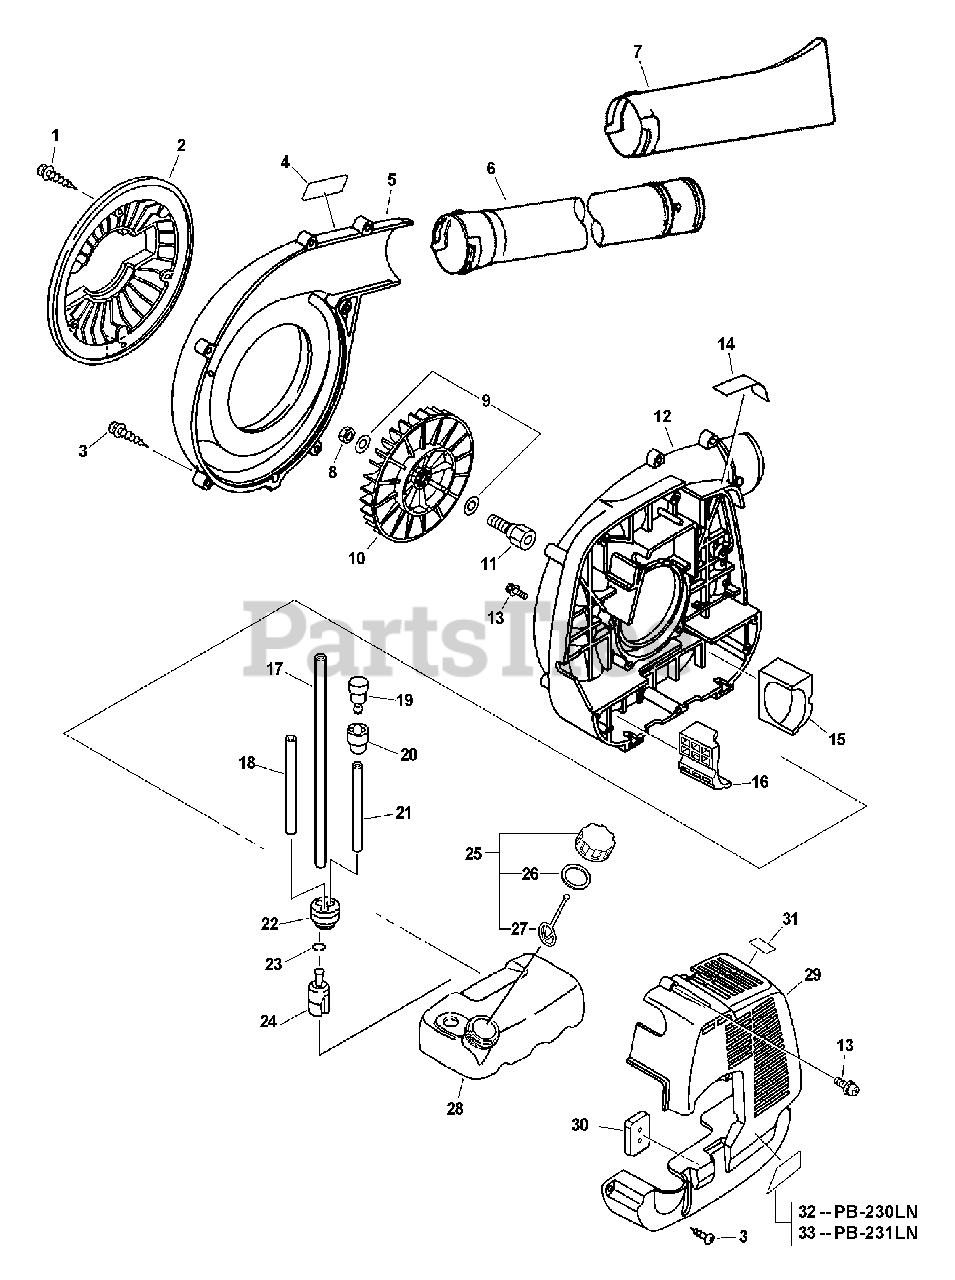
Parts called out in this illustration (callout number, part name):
1	SCREW - 5X16 -- TAPPING
2	GUARD, DEBRIS
3	SCREW - 5X20 -- TAPPING
4	LABEL - NOISE 65dB(A) CAT I
5	COVER, FAN - OUTER
6	TUBE, BLOWER - STRAIGHT
7	TUBE, BLOWER - NOZZLE
9	WASHER - 8
11	HUB, FAN
12	COVER, FAN - INNER
13	SCREW - 5X20
14	LABEL - CAUTION
15	CUSHION, FUEL TANK - RIGHT
16	CUSHION, FUEL TANK - LEFT
17	PIPE - 3X6X200 -- BLACK
18	PIPE - 3X6X100 -- CLEAR
19	VENT, FUEL TANK
20	COVER, VENT
21	PIPE - 3X6X100 -- BLACK
22	GROMMET
23	CLIP - 6.5
24	FILTER, FUEL
25	CAP ASSY - ORANGE
26	GASKET, CAP
27	CONNECTOR, CAP
28	TANK, FUEL
29	COVER, ENGINE
30	CUSHION, FUEL TANK - FRONT
31	LABEL - HOT SURFACE
32	LABEL - MODEL PB-230LN
33	LABEL - MODEL PB-231LN
